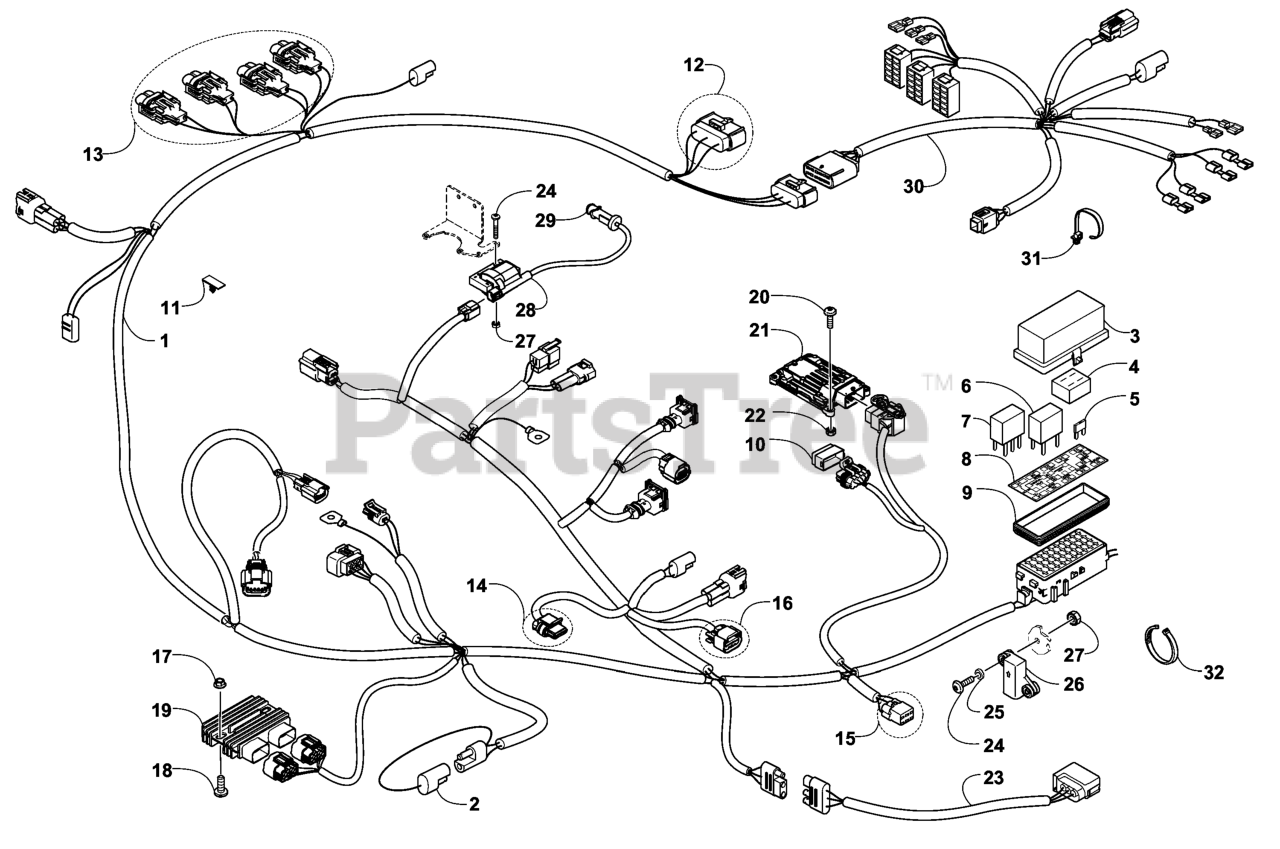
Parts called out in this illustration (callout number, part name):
1	HARNESS-DIA, MAIN
2	TETHER-REAR ACCESSORY CON
4	HOLDER-SPARE FUSE
5	FUSE-MINI, 10A
5	FUSE-MINI, 15A
5	FUSE-MINI, 30A
6	RELAY-SPST
7	RELAY-SPDT
8	DECAL-PDM
9	SEAL-PDM
10	COVER ASM
11	RETAINER-CLIP, HARNESS
12	KIT-CAN GAUGE CONNECTOR
13	KIT-HL CONNECTOR REPAIR (
14	KIT-REPAIR, ISC
15	KIT-TILT SENSOR CONNECTOR
16	KIT-REPAIR, 4P TMAP CONNE
17	NUT-HHF
18	SCREW-TSPRH
19	REGULATOR-VOLTAGE
20	SCREW-TSPRH
21	ECM-PROGRAMMED
22	NUT-HH, SEMS
23	HARNESS-ADAPTER, TAIL LIG
24	SCREW-TSPNH
25	WASHER-FLAT
26	SENSOR-INCLINATION
28	COIL/CAP, IGNITION ASM
29	CAP-SPARK PLUG
30	HARNESS-CONSOLE
31	TIE-CABLE
32	TIE-CABLE
